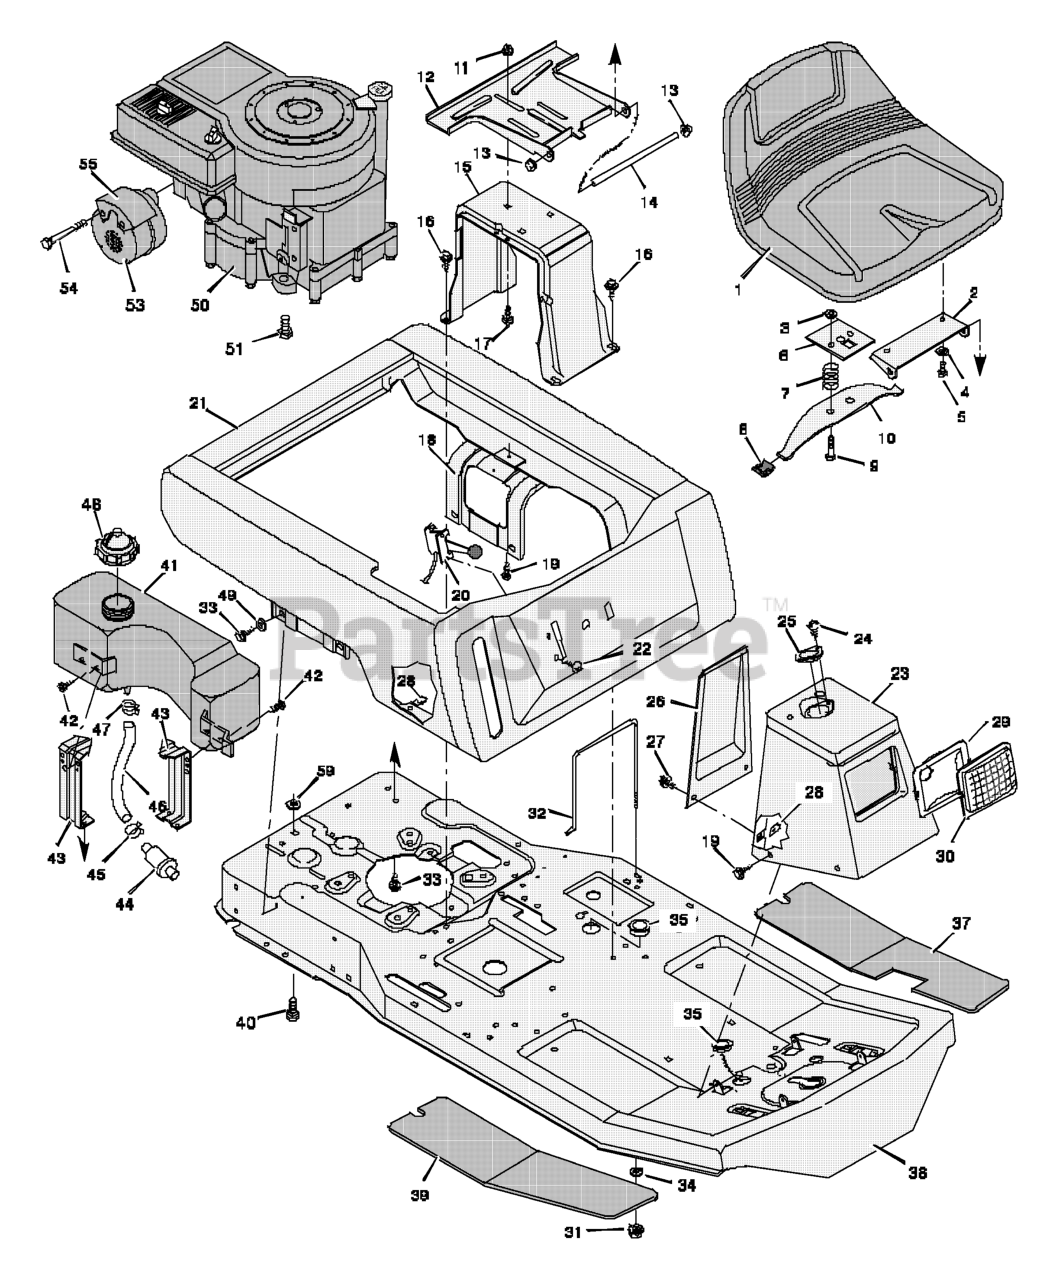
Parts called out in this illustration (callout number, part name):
2	Hinge, Seat
3	Retainer
4	Lockwasher
5	Bolt, Hex
6	Plate, Seat Switch
7	Spring, Compression
8	Glide, Seat Spring
9	Bolt, Shoulder
10	Spring, Seat
11	Locknut, Flange
12	Bracket, Seat Pivot
13	Cap, Push on
14	Rod, Seat Hinge
15	Support, Seat
17	Bolt, Carriage
18	Support, Body
20	Throttle Control
23	Console Assembly
25	Bearing, Steering Post
26	Console, Plate
29	Reflector
31	Locknut
32	Clamp, Battery
35	Grommet
37	Mat, Left
38	Frame Assembly
39	Mat, Right
40	Bolt, Carriage
41	Tank, Fuel
43	Bracket, Fuel Tank
44	Filter, Fuel
46	Line, Fuel
47	Clamp
48	Cap, Fuel
49	Washer
50	Engine *
51	Bolt, Engine Mount
53	Muffler
55	Shield, Heat
59	Washer
